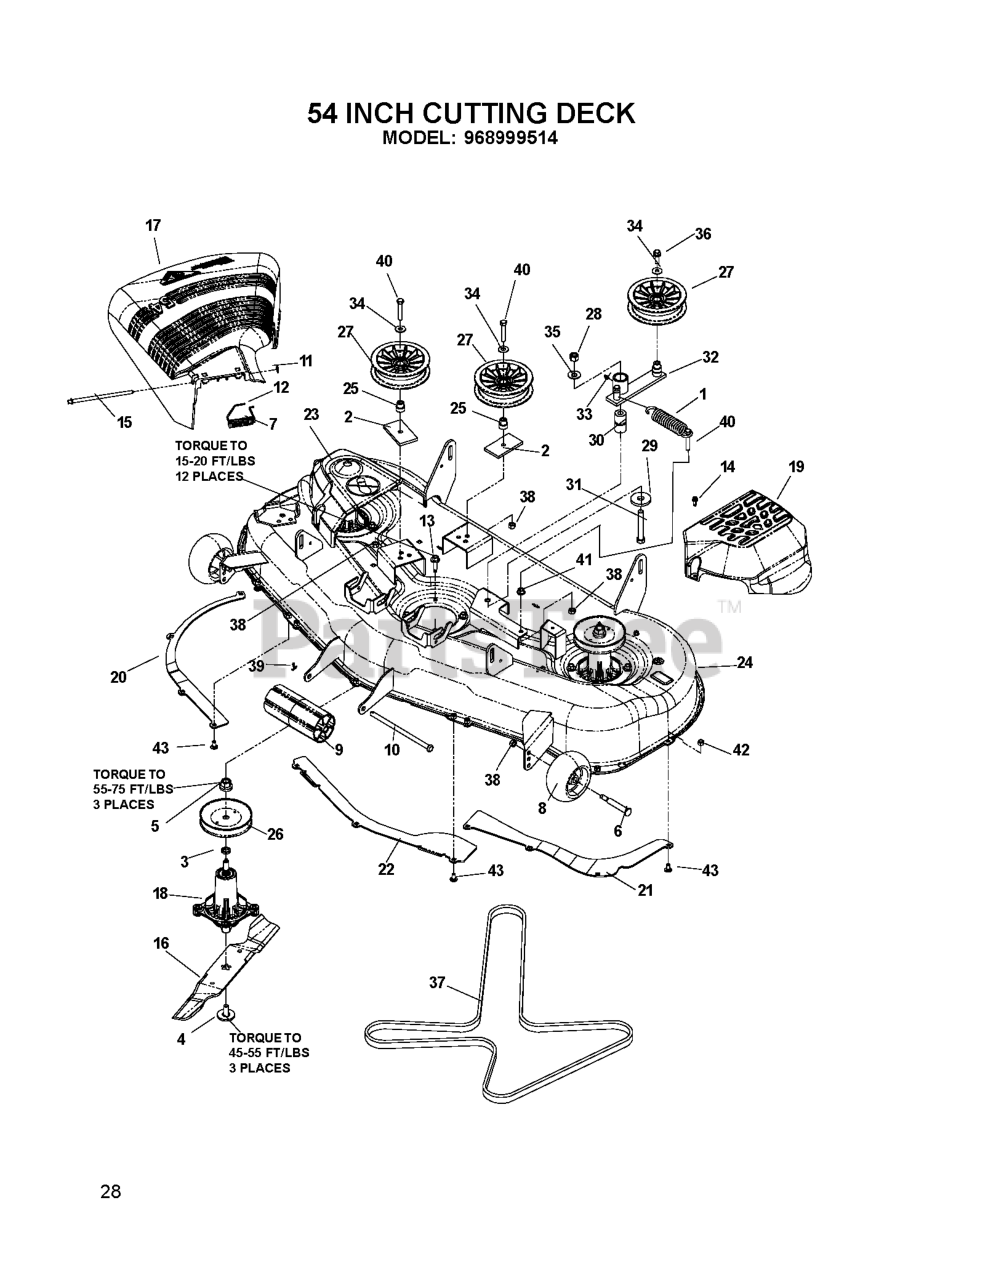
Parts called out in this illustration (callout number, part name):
2	DRAWBAR.LOWER.2PC.18/22
3	RP LOGO
5	ASM.DASH.HUSQ.GT.ROUND.ELE.CK
14	HOOD
15	LENS.LH.TEX.GT.HUSQ.CL
18	GRILL.ASM.HUSQ.TG/CRD.W/TRIM
25	LENS.RH.TEX.GT.HUSQ.CL
36	SCREW 5/16"
37	FENDER.PNT.TX.GT.CH/FW.ORANGE
58	DRAWBAR.UPPER.2PC,LRG.FENDER
68	Screw 5/16-18 x 1/2 Hex, Self Tapping 5/16-18 x 1/2
130	SCREW.#10 X 0.750.BOS
137	BUMPER DASH
150	AIR.DUCT.HOOD.TEX.GT.HUSQ
152	SHIELD.BROWNING/DEBRIS
159	SCREW, 3/8-16X3/4
161	CONSOLE.FUEL.WINDOW.HU
162	SCREW.HI-LO.CONSOLE
165	SUPPORT.TANK.REAR.B/TE
175	PLATE.CROSSMEMBER.HUSQ
176	SCREW.#10-24X5/8.RN.QU
177	BUSHING, STEERING
178	CARGO.ASM.NET.TXGT.W/C
180	CHASSIS.STAMPING.LT/GT
181	BUSHING.MNT.FEND.CRGO.
182	DASH.LOWER.COMMON.12V.ADAPTOR
183	BOLT.5/16-18X1-1/4 FULL THD
189	SCREW
194	NUT LOCK HEX FLANGE 5/16-18
196	CONSOLE.ASM.DCKLFT.W/RF.HQ.DLR
199	PLATE.DECK.LIFT.HUSQVARNA.GT
202	VENT.SIDE.HOOD.HUSQ.RH.GREY
203	VENT.SIDE.HOOD.HUSQ.LH.GRAY
204	HOOD VENT
205	SKIRT.HOOD.SIDE.HUSQ.RH.GREY
206	SKIRT.HOOD.SIDE.HUSQ.LH.GREY
207	BEZEL.RH.TEX.GT.HUSQ
208	BEZEL.LH.TEX.GT.HUSQ
209	INSERT.HEX.GRILL.HUSQ.GREY
210	INSERT.HEX.GRILL.HUSQ.
211	INSERT.HEX.GRILL.HUSQ.
212	INSERT.HEX.GRILL.HUSQ.
214	CLIP.RETAINER.TINNER.
217	ROD.PIVOT.HOOD
221	REFLECTOR.LH.TEX GT HU
228	STUD.FASTNER.W/ANTI-ROTATE
234	BUMPER.HOOD.TEX.HUSQVARNA
235	SPACER FENDER
236	NUT.CENTERLOCK.5/16-
238	TRIM.HUSQ.TG/CRD.SERVICE
298	NUT PUSH M
